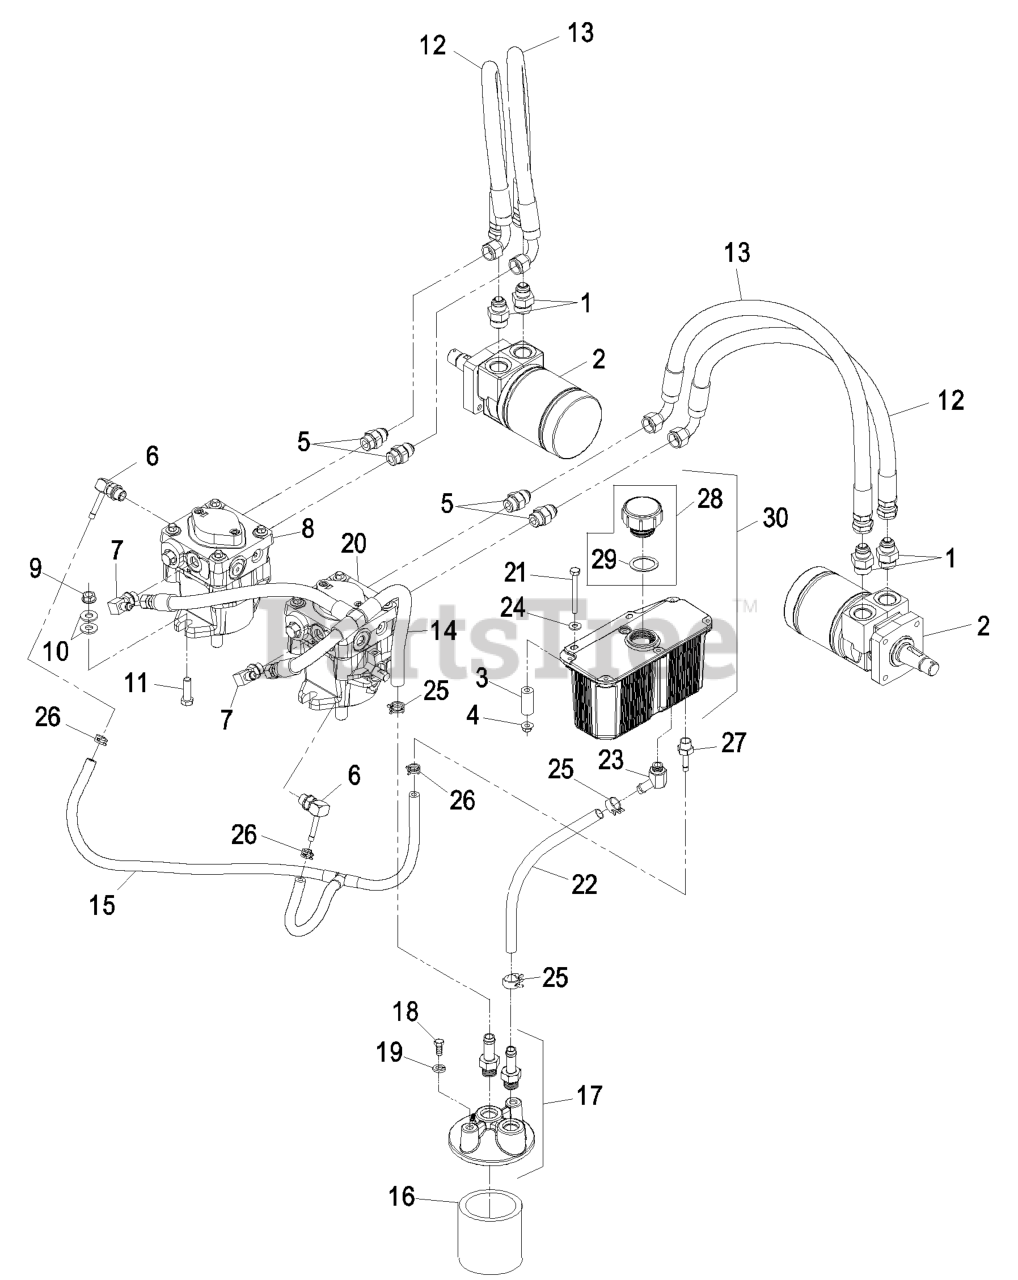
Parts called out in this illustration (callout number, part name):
1	FITTING-STRAIGHT
2	HYD MOTOR ASM
5	FITTING-STRAIGHT
6	ELBOW-90 DEG
7	FITTING-ELBOW, 90 DEG
8	PUMP-HYD
9	NUT-HHF, WHIZ
10	WASHER-FLAT
11	SCREW-HH
13	HOSE-PRESSURE, HIGH
14	CHARGE HOSE ASM
15	CASE DRAIN HOSE ASM
16	FILTER-25 MICRON, BI-DIRE
17	FILTER HEAD ASM
18	SCREW-HH
19	WASHER-LOCK
20	PUMP-HYD
21	SCREW-HH
22	HOSE-CHARGE
23	FITTING-BARBED, 45 DEG
24	WASHER-FLAT
25	CLAMP-HOSE
26	CLAMP-HOSE
27	ADAPTER-STRAIGHT
28	KIT,HYD RES CAP W/GASKET
29	GASKET-CAP
30	HYD RESERVOIR ASM
